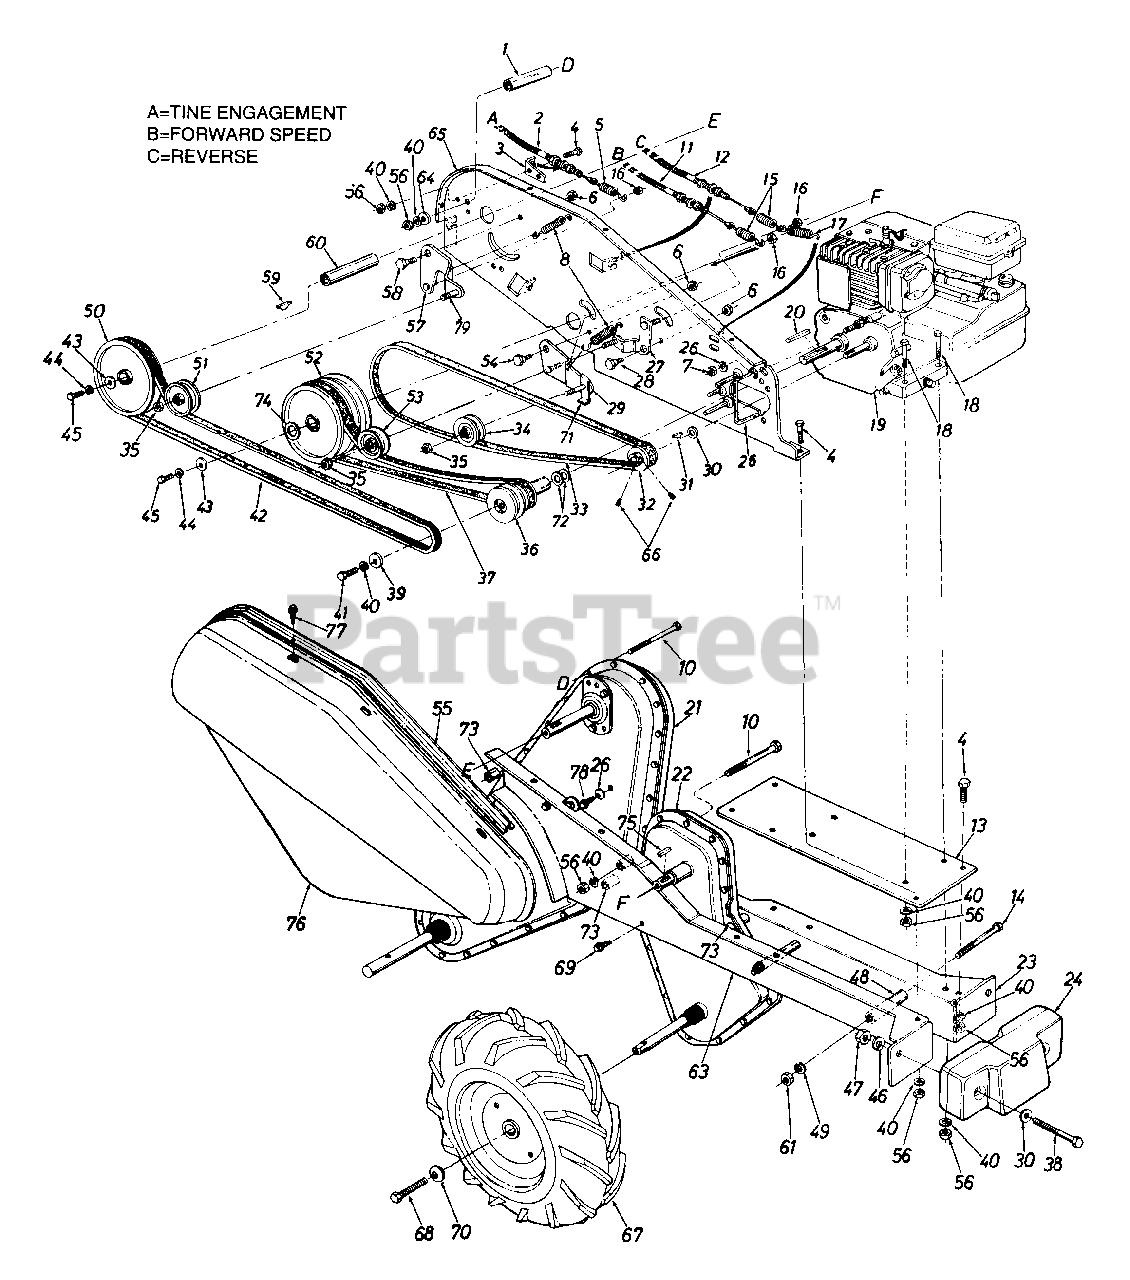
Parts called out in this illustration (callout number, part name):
1	Spacer .375" I.D. x .5" O.D. x 2" Lg.
2	Clutch Control Cable (Tines)
3	Clutch Cable Bracket
4	Hex Bolt 5/16-18 x .75" Lg.
5	Extension Spring .50" O.D. x 2.5" Lg.
6	Hex Cent. L-Nut 3/8-16 Thd.
7	Hex Nut 1/4-20 Thd.
8	Extension Spring .50" O.D. x 1.55" Lg.
10	Hex Bolt 5/16-18 x 3" Lg.
11	Clutch Control Cable 42" Lg. (Forward)
12	Clutch Control Cable 42" Lg. (Reverse)
15	Springs
16	Hex Cent. L-Nut 1/4-20 Thd.
17	Extension Spring .41" O.D. x 2.05" Lg.
18	Hex Bolt 5/16-18 x 1.5" Lg.
19	Engine
20	Sq. Key 3/16 x 1.00" Lg.
21	Chain Case Comp. - Tines
22	Chain Case Comp. - Wheels
25	Belt Keeper
26	Bell-Wash. .265" I.D. x .75" O.D.
29	Idler Brkt. Ass'y. (Wheel Forward)
30	Fl-Wash. .51" I.D. x 1.0"
31	#5 Hi-Pro-Key 1/8" x 5/8" Dia.
32	1/2" V-Pulley 2.25" O.D. x .503" I.D.
33	"V"-Belt
34	"V"-Belt Idler 2.62" O.D.
35	Hex Ins. L-Nut 3/8-24 Thd.
36	1/2" "V"-Pulley Ass'y.
37	"V"-Belt
38	Hex Bolt 1/2-13 x 4" Lg.
39	Fl-Wash. .344" I.D. x 1.125"
40	L-Wash. 5/16" I.D.
41	Hex Bolt 5/16-24 x 1.00" Lg.
42	"V" Belt
43	Fl-Wash. 1/4" I.D. x .93" O.D.
44	L-Wash. 1/4" I.D.
45	Hex Bolt 1/4-28 x .75" Lg.
46	L-Wash. 1/2" I.D.
47	Hex Nut 1/2-13 Thd.
48	Spacer .38" I.D. x .62" O.D. x 2.18" Lg.
49	L-Wash. 3/8" I.D.
50	Fl-Pulley w/Flanges 6" O.D.
51	Fl-Idler w/Flanges 3.75" O.D.
52	Double Fl-Pulley 5/8" I.D.
53	Fl-Idler w/Flanges 2.12" O.D.
54	Shld. Bolt .500" Dia. x .170" Lg.
55	Flange Extension
56	Hex Nut 5/16-18 Thd.
59	#61 Hi-Pro-Key 3/16" x 5/8" Dia.
60	Spacer .647" I.D. x 2.75" Lg.
61	Hex Nut 3/8-24 Thd.
65	Side Plate Ass'y.
66	Set Scr. 1/4-28 x .25" Lg.
67	R.H. Wheel Ass'y. Comp. 13 x 5
68	Hex Bolt 5/16-24 x .62" Lg.
69	Hex Self-Tap Scr. 5/16-24 x .5" Lg.
70	Bell-Wash. 5/16" I.D.
71	Belt Keeper Brkt.
72	Fl-Wash. .76" I.D. x 1.5"
73	Spacer .326" I.D. x .47" O.D. x .96" Lg.
74	Fl--Wash. 5/8" I.D. x 1" O.D.
75	Sq. Key 3/16 x .75" Lg.
78	Hex Wash. S-Tap Scr. 1/4-20 x .38" Lg.
79	Hex Bolt 3/8-24 x 1.25" Lg.
A	Tine Engagement
B	Forward Speed
C	Reverse
